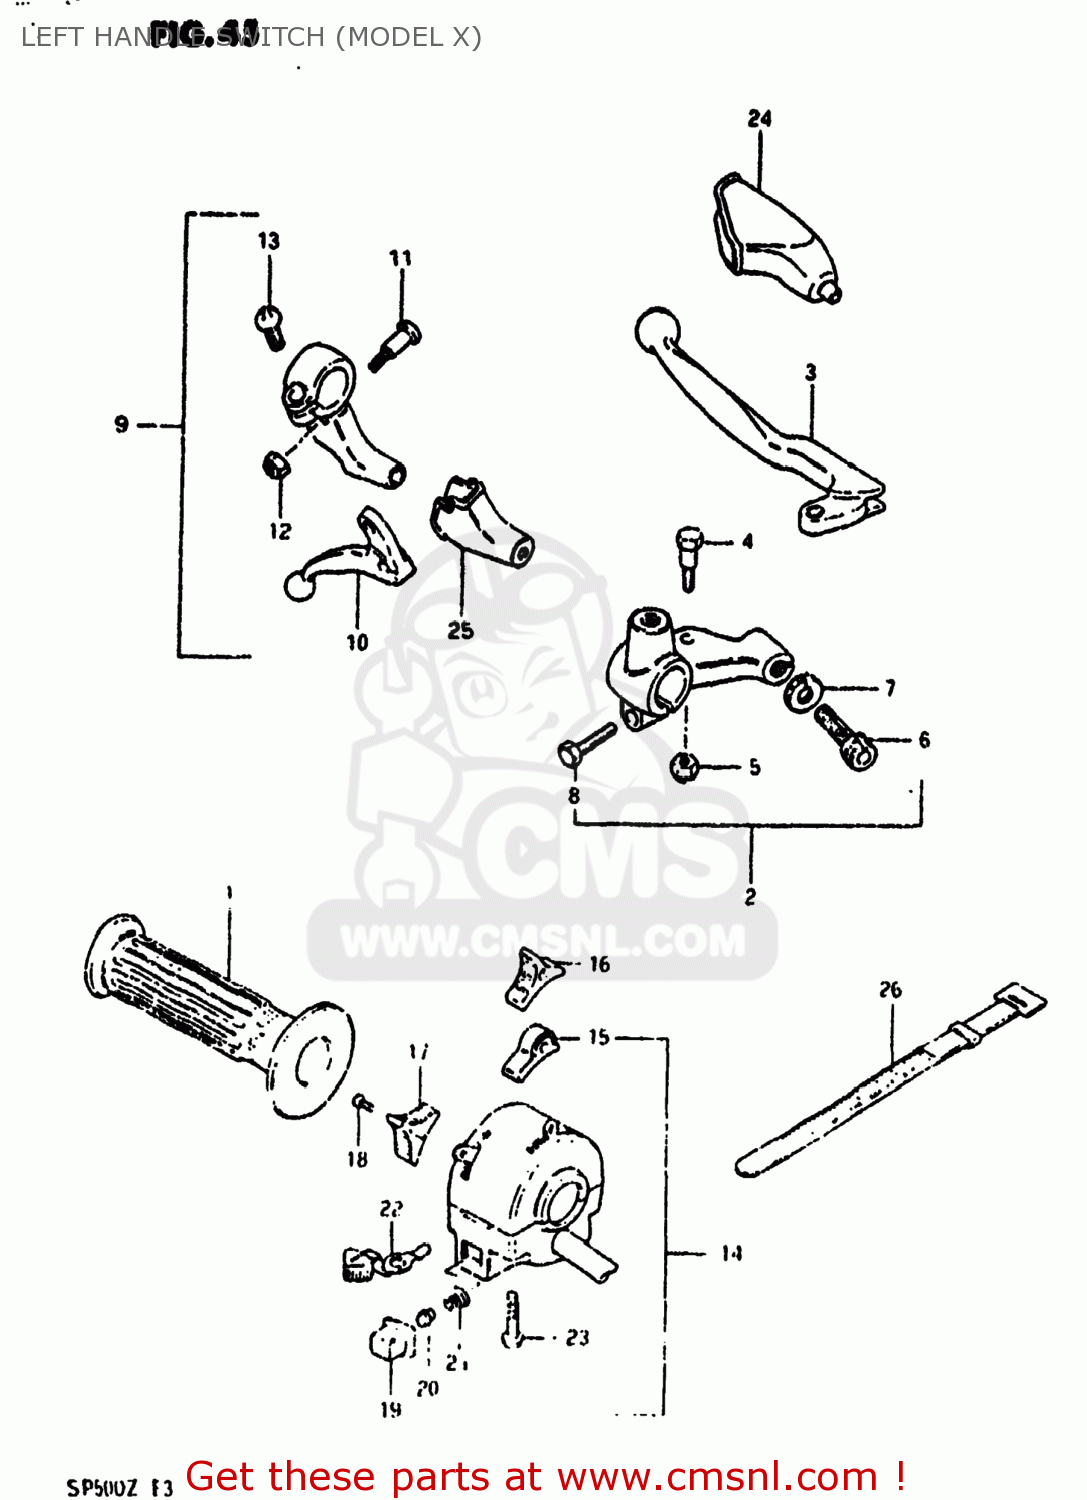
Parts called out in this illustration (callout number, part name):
1	GRIP,L
2	LEVER ASSY,CLUTCH
3	LEVER,CLUTCH
4	BOLT,LEVER
5	NUT 6MM
6	ADJUSTER,CABLE
7	NUT,CABLE ADJUSTER
8	BOLT
9	LEVER ASSEMBLY,DECOMPRESSION
10	LEVER,DECOMPRESSION
11	BOLT,LEVER
12	NUT,LEVER BOLT
13	SCREW
14	SWITCH ASSEMBLY,HANDLE,LEFT
15	KNOB,STOP
16	KNOB,LIGHTING SWITCH
17	KNOB,DIMMER SWITCH
18	SCREW
19	BUTTON,HORN
20	CONTACT
21	SPRING
22	KNOB,TURNSIGNAL
23	SCREW
24	COVER,CLUTCH LEVER
25	COVER,DECOMP LEVER DUST
26	CLAMP
